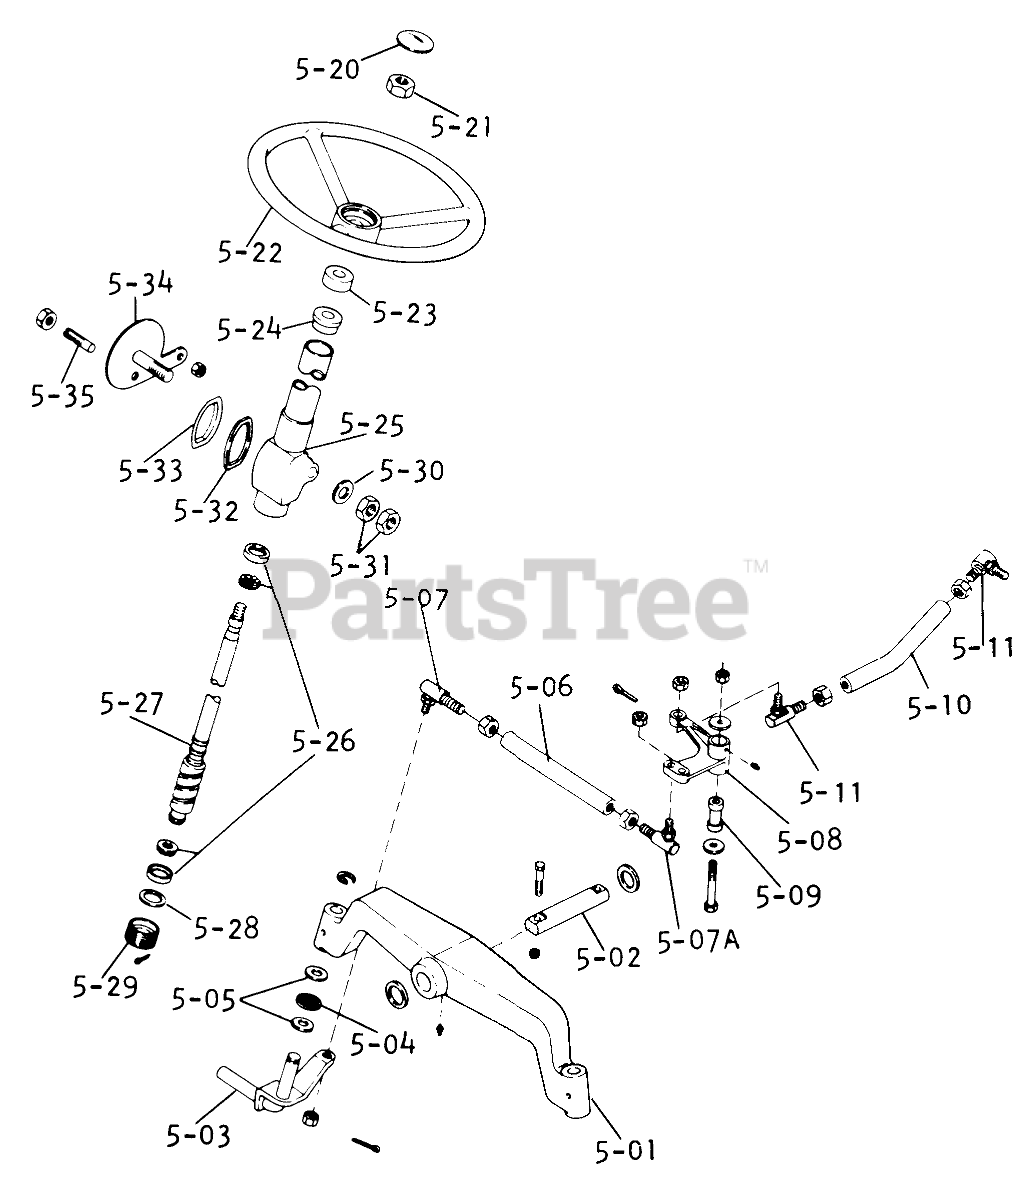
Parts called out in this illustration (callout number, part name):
5-01	Axle-Front
5-02	PIN AXLE
5-03	Spindle Assy. R.H.
5-04	BEARING-THRUST
5-05	Race Thrust
5-06	TIE ROD R
5-07	Ball Joint RH
5-07A	LH BALL JOINT R
5-08	Bell Crank-Steering
5-09	Bushing
5-10	Drag Link
5-11	BALL JOINT-SHORT R
5-20	STEERING WHEEL INSE
5-21	Nut-5/8-18
5-22	Steering Wheel
5-23	Cover-Dust
5-24	Column Bearing
5-25	Assy-Housing and Column
5-26	BALL CUP KIT
5-27	Steering Gear
5-28	WASHER
5-29	Adjusting Plug
5-30	Washer 49/64 X 1 1/4
5-31	Nut, 3/4-16
5-33	Retainer-Seal
5-34	Lever
5-35	Stud
